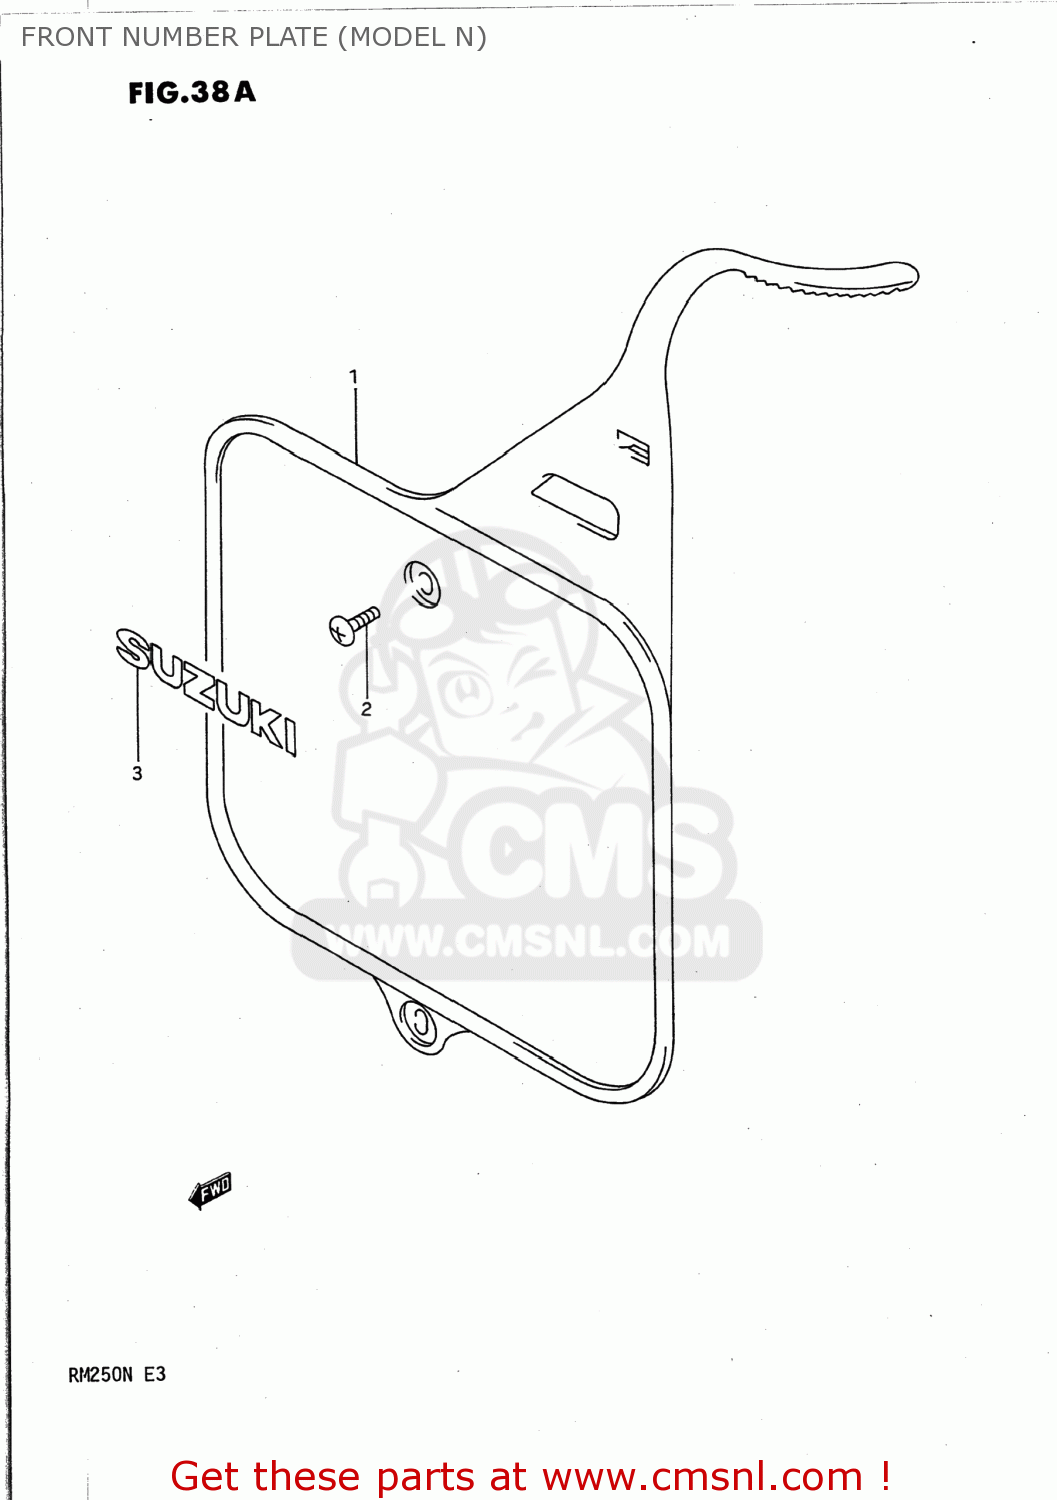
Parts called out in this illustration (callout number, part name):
1	PLATE,NUMBER,FRONT
2	SCREW
3	EMBLEM,FRONT NUMBER PLATE (SUZUKI)
